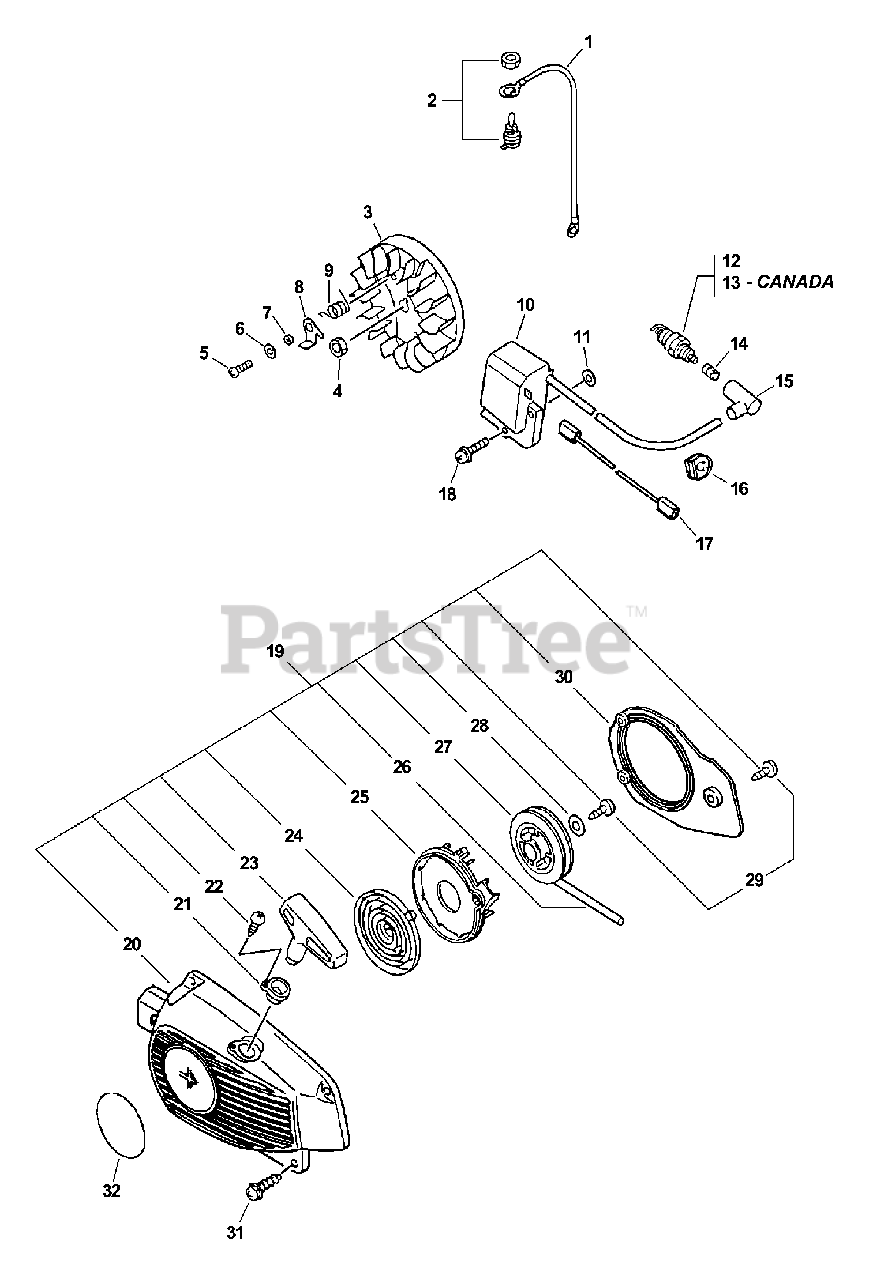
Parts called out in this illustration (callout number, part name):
1	LEAD - GROUND
2	IGNITION SWITCH KIT
3	FLYWHEEL
4	NUT - 8 -- FLANGE
5	SCREW - 5X12
6	WASHER - 5
8	PAWL, STARTER
9	SPRING, RETURN
10	COIL, IGNITION
12	SPARK PLUG -- BPM-8Y
13	SPARK PLUG -- BPMR-8Y
14	TERMINAL, SPARK PLUG CAP
15	CAP, SPARK PLUG
17	LEAD - IGNITION
18	SCREW - 5X22
19	STARTER ASSY
20	CASE, STARTER - GRAY
21	GUIDE, ROPE
22	SCREW - 3X14
23	GRIP, STARTER
24	REWIND SPRING ASSY
25	PLATE, STARTER
26	ROPE, STARTER - 3X850
27	REEL, ROPE
29	SCREW - 4X14
31	SCREW - 4X16
32	LABEL - ECHO
